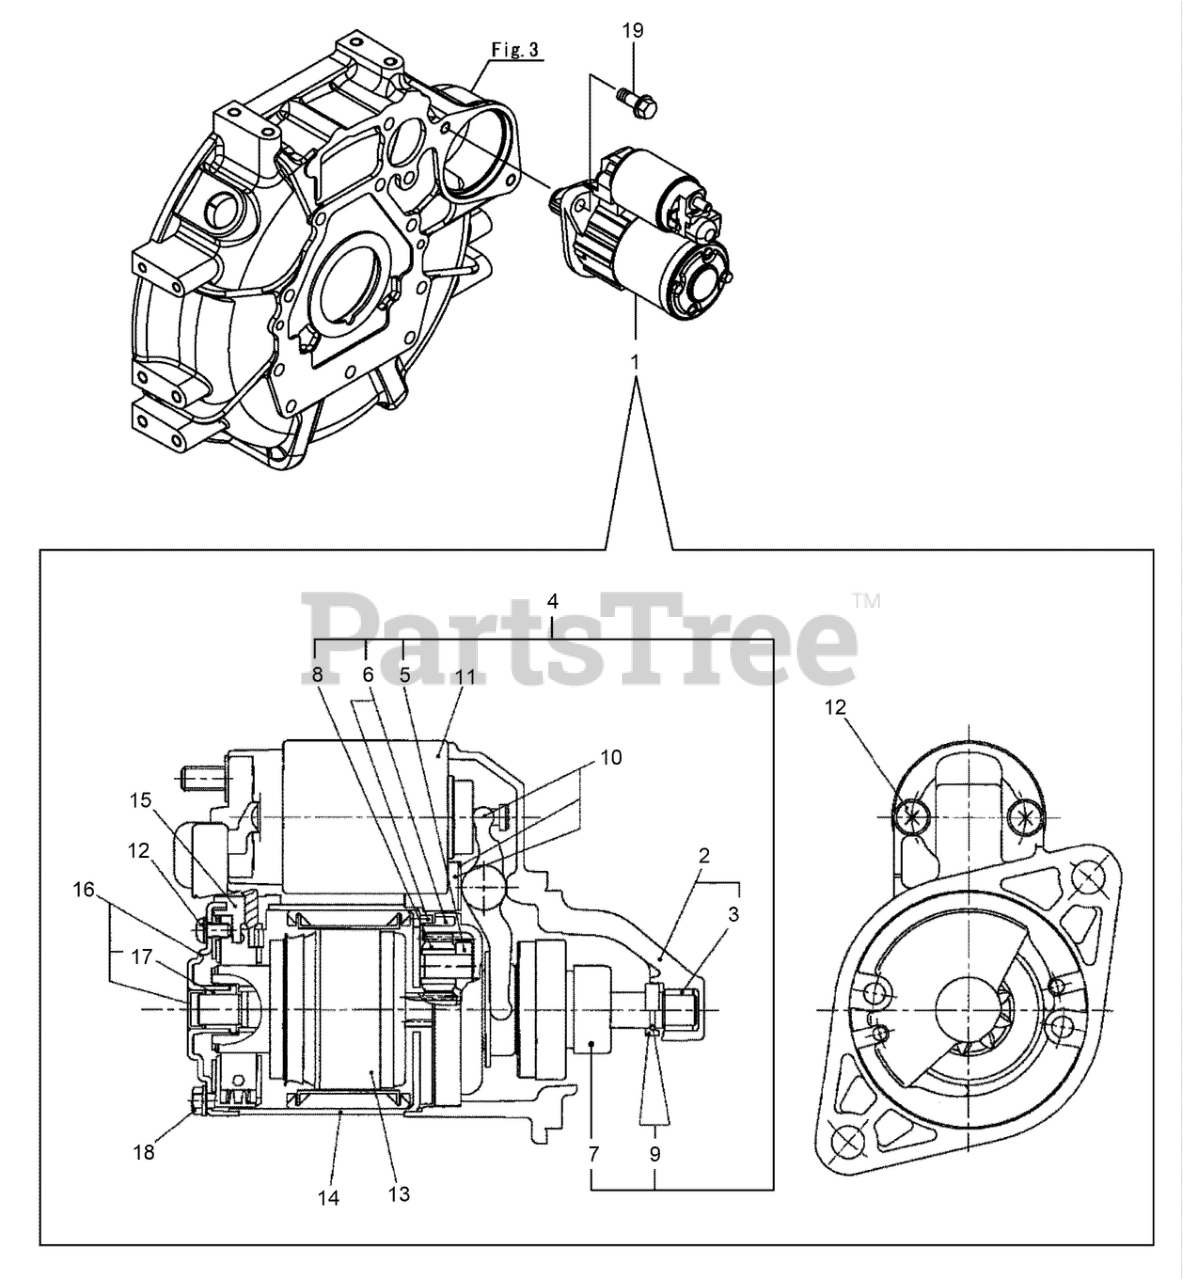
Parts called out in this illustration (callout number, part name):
1	STARTER, 12V-1.1KW
2	BRACKET ASSY, FRONT
3	METAL, FR
4	SHAFT ASSY, CLUTCH
5	SHAFT ASSY, GEAR
6	GEAR ASSY, INTERNAL
7	CLUTCH, OVER RUNNING
8	GEAR ASSY
9	STOPPER SET
11	SWITCH ASSY
12	SCREW SET
13	ARMATURE
14	YOKE ASSY
15	BRUSH ASSY
16	COVER ASSY
17	METAL, RR
18	BOLT SET
